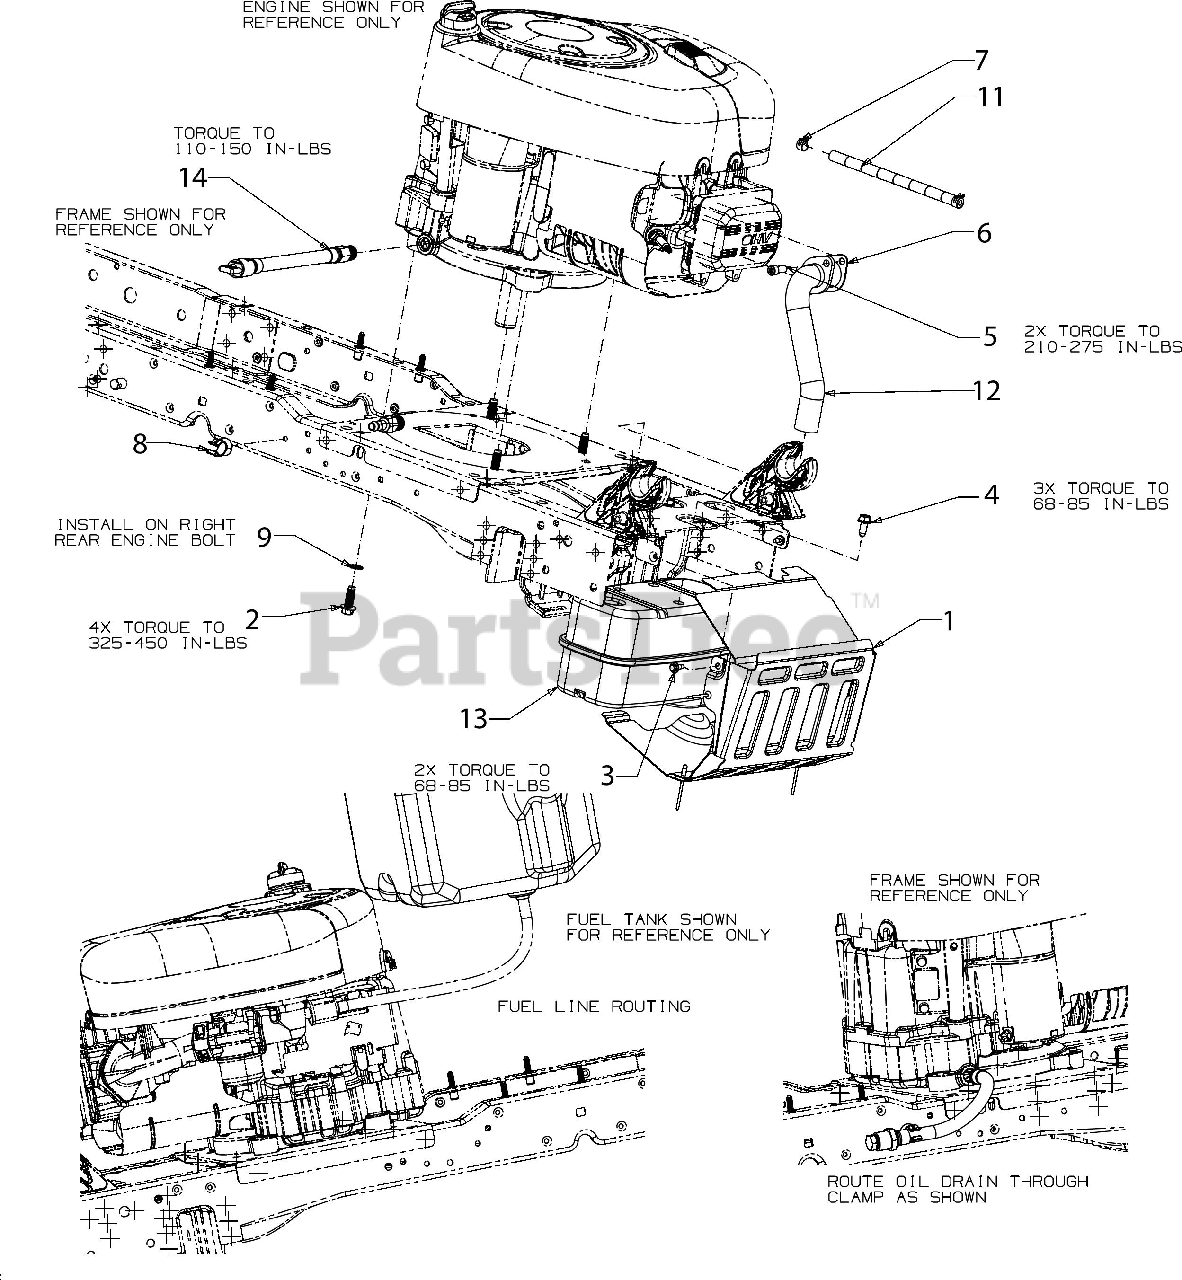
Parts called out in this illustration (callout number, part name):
1	MUFFLER SHIELD ASSEMBLY
2	SCREW 3/8-16 x 1
3	SCREW M6-1 x .625
4	SCREW M8-1.25 x .750
5	SCREW 5/16-18 x .625
6	EXHAUST GASKET
7	HOSE CLAMP 1/20
8	DRAIN HOSE CLIP
9	LOCK WASHER 3/8
11	FUEL HOSE LOW PERMEATION
12	EXHAUST PIPE (B&S) (SINGLE)
13	EXHAUST MUFFLER (SINGLE)
14	OIL DRAIN HOSE 3/8 NPT
